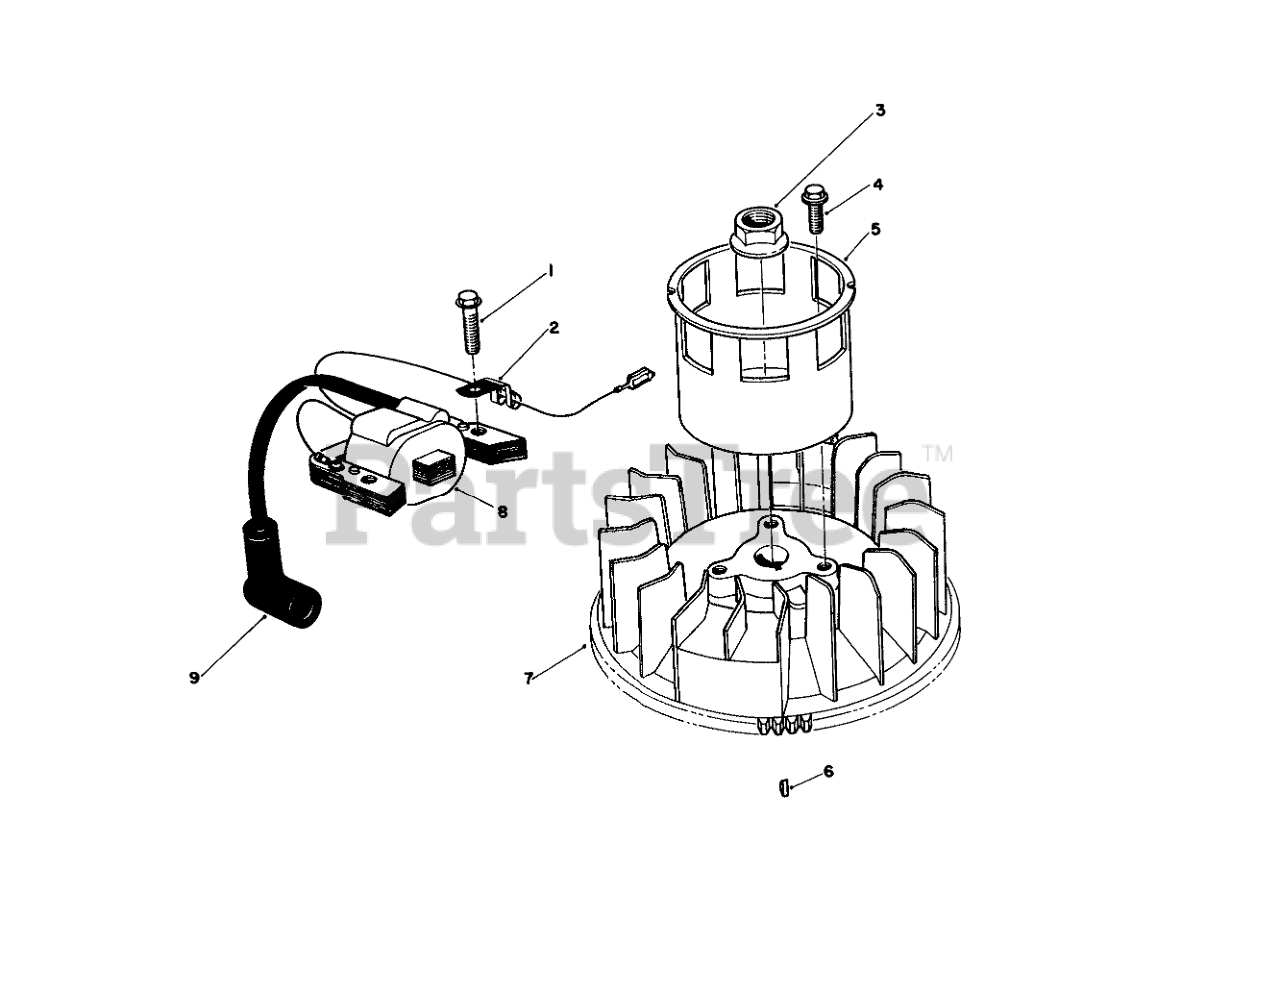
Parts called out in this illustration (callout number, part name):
2	CLAMP
7	FLYWHEEL
8	COIL
9	COVER
